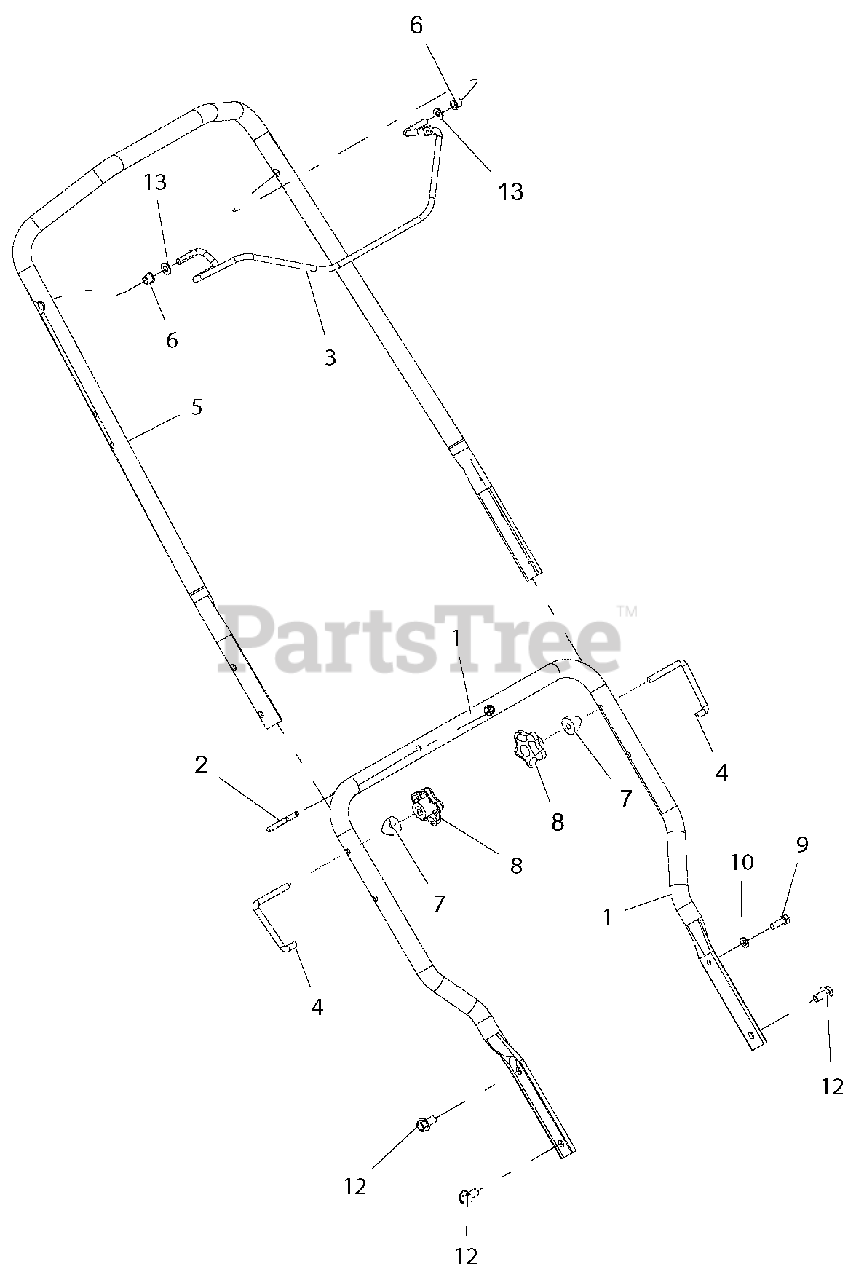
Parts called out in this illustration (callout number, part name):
1	HANDLEBAR, LOWER W/DECAL
2	GUIDE, PULL CORD
3	BAIL, AUGER
4	PIVOT, BOLT, HANDLEBAR
5	HANDLEBAR, UPPER W/DECAL
6	BSHG-FLG .325X.444X.440X.560
7	SPACER, HANDLEBAR
8	KNOB, STAR, 5/16-18UNC
9	BLT-HEX .31-24X.875 GR5YZ EP80
10	@WSHR-LK .31X.078 REG YWZC
12	BLT-SERHFWH .38-16X.75 YWZC
13	@WSHR-FL-STL.344X.688X.065YWZC
